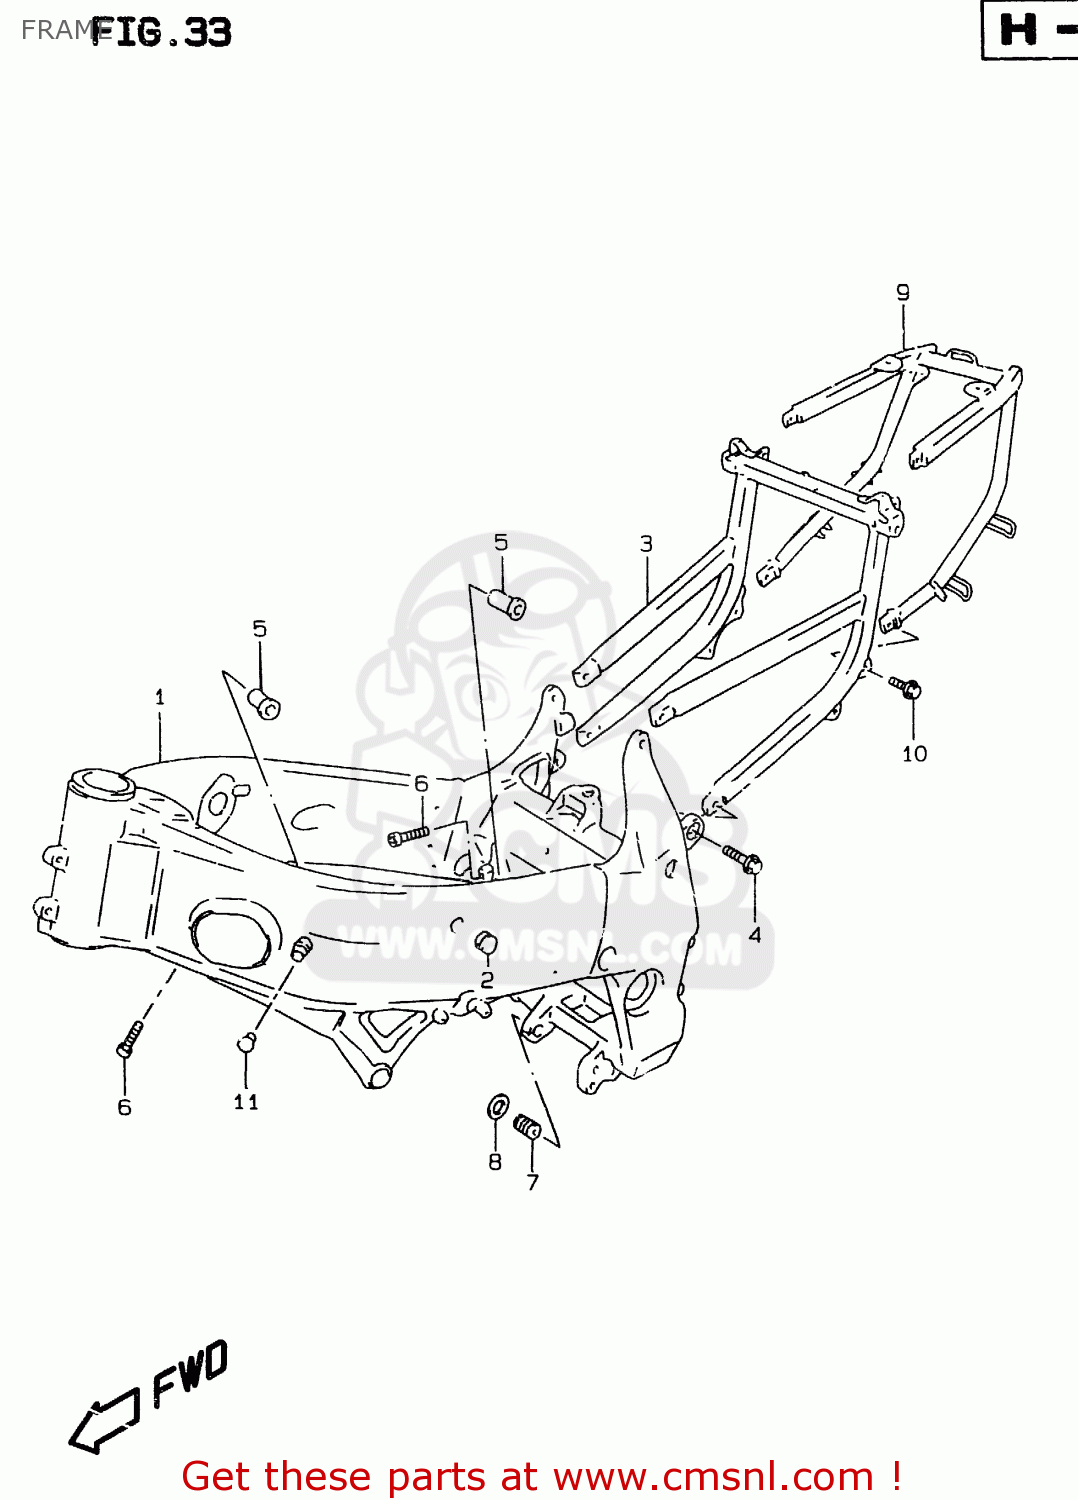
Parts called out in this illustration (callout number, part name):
1	FRAME COMP
2	CAP,TANK RAIL
3	RAIL,SEAT
4	BOLT(10X30)
5	SPACER,ENGINE MOUNTING
6	BOLT
7	BOLT,CRANKCASE ADJUST
8	NUT,CRANKCASE ADJUST
9	GRIP,RR
10	BOLT
11	CAP
